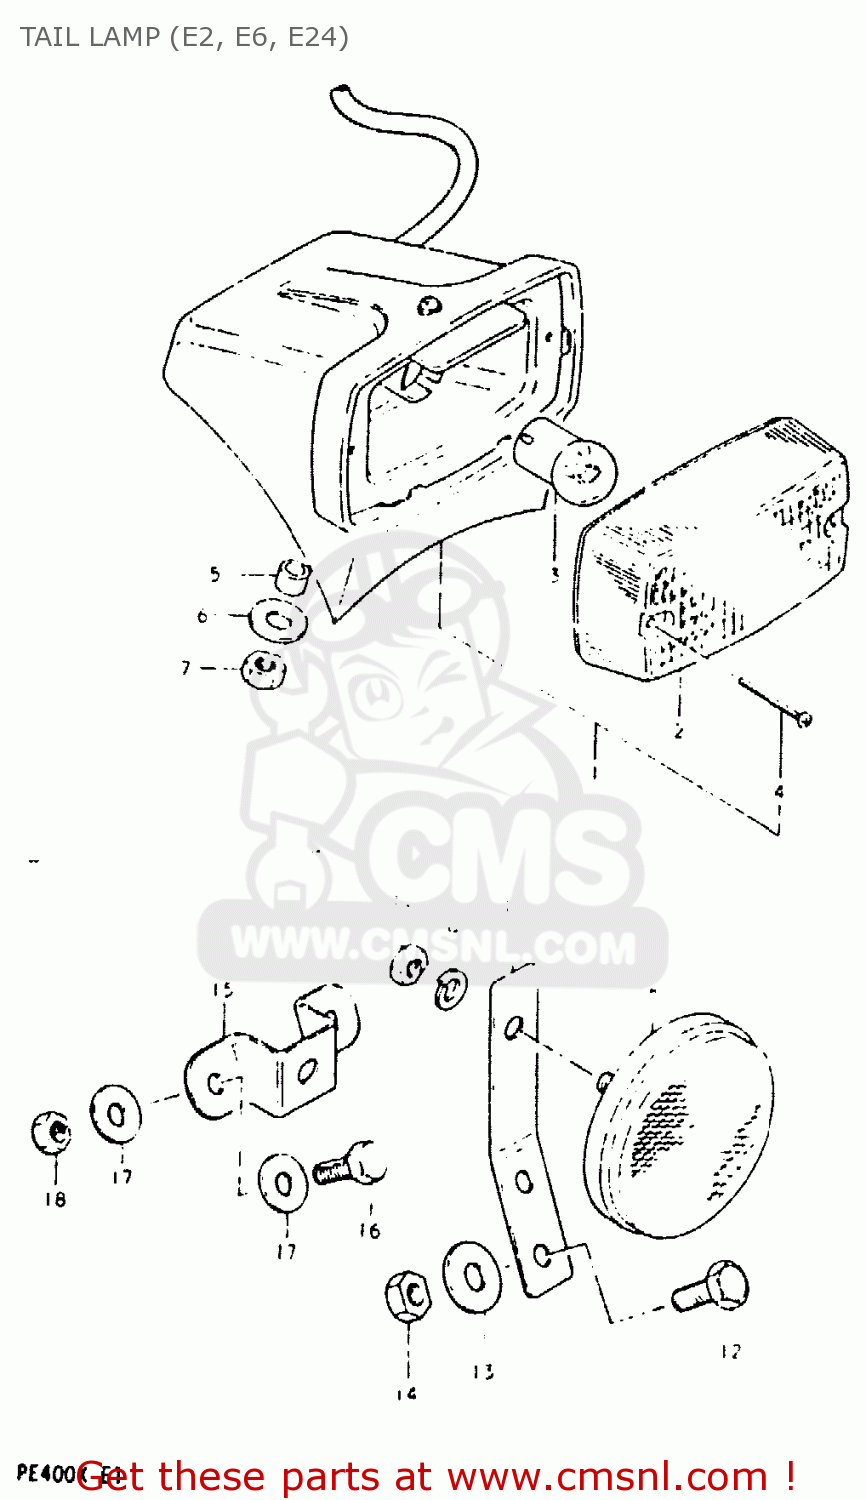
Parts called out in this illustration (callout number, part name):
1	LAMP ASSY, TAIL
2	LENS
3	BULB(6V17/5.3W,STANLEY,A4813)
4	SCREW,REAR COMBINATION LAMP LENS
5	SPACER (6.1X9X9)
6	WASHER
7	NUT
8	REFLEX REFLECTOR,RR
9	LOCK WASHER
10	NUT
11	BRACKET
12	BOLT
13	WASHER
14	NUT
15	BRACKET
16	BOLT
17	WASHER
18	NUT
